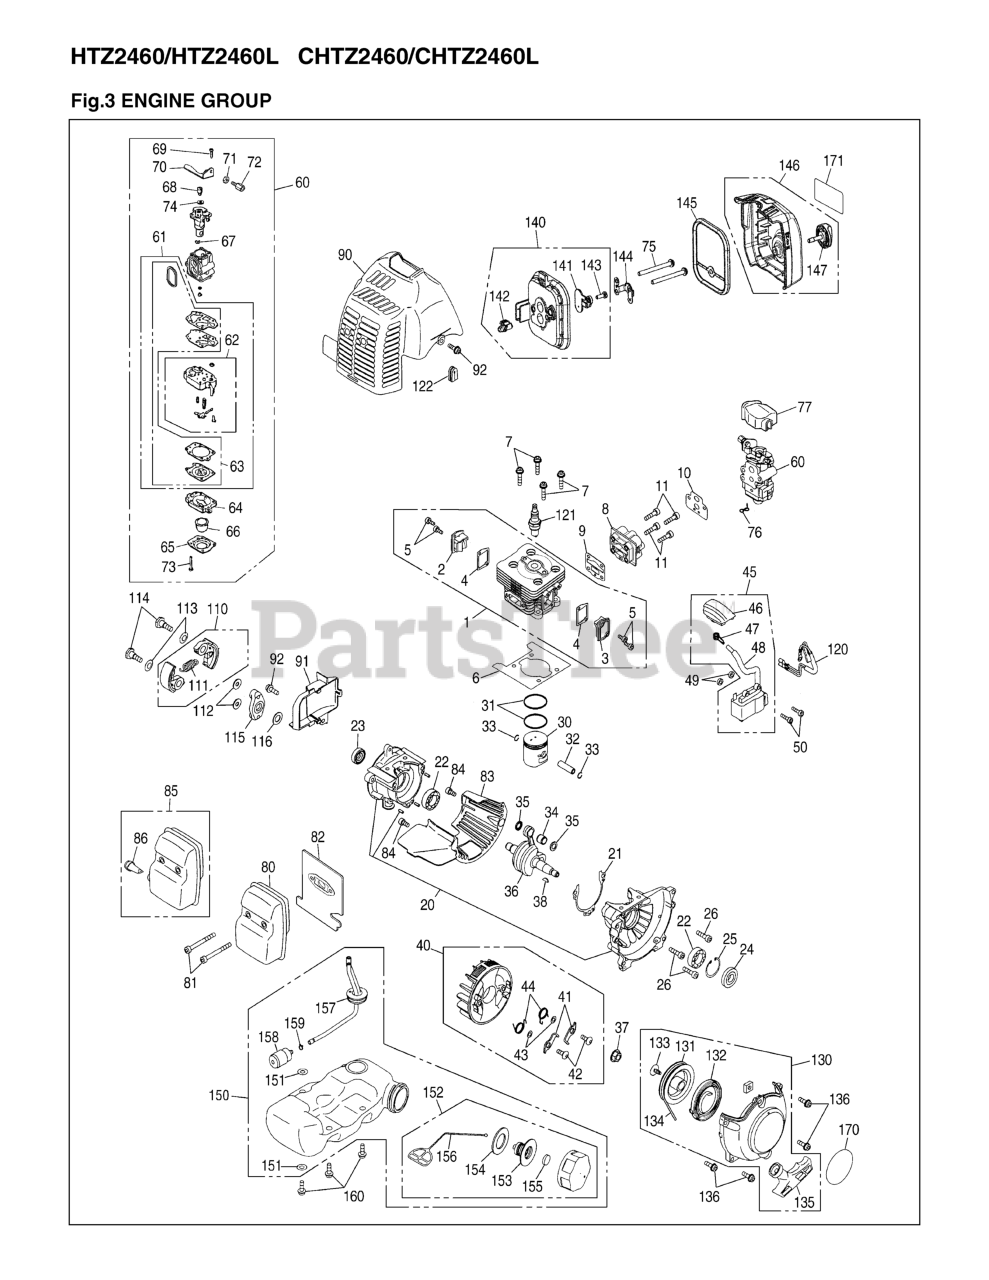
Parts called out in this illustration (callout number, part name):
1	CYLINDER-C
2	COVER, TR-S
3	COVER, TR-F
4	GASKET, TR
5	BOLT
6	GASKET,BASE
7	BOLT
8	INSULATOR
9	INSULATOR GASKET
10	GASKET, CARB
11	BOLT, TORX
20	CRANKCASE COMP.(
21	GASKET, CASE
22	BEARING MAIN
23	SEAL
24	SEAL, OIL (RPLS
26	BOLT (RPLS 28501
31	RING, PISTON
32	PIN, PISTON
33	RING, SNAP (RPLS
35	WASHER
36	SHAFT COMP. (RPL
37	NUT (RPLS 1140-4
38	KEY
40	ROTOR ASSY
41	PAWL
42	SCREW
43	WASHER
45	COIL-A
46	CAP(RPLS 4810721
50	BOLT TORX
60	CARBURETOR ASSY.
61	REBUILD KIT
62	BODY, PUMP
63	GASKET KIT
64	BODY, PURGE
65	COVER, PUMP
66	PUMP, PRIMING
72	SCREW
73	SCREW
74	WASHER
75	BOLT TORX
76	CLIP
77	COVER
81	BOLT
82	MUFFLER GASKET
84	BOLT
90	COVER,ENGINE
91	DEFLECTOR
92	BOLT, TORX
110	CLUTCH ASSY
112	WASHER
113	WASHER
115	PLATE, CLUTCH
116	WASHER
121	SPKPLUG(CMR7H)(R
122	GROMMET
130	RECOIL-A
132	SPRING, SPIRAL
133	SCREW (RPLS 1850
135	KNOB (RPLS 3330-
136	BOLT, TORX
140	BODY ASSY
141	PLATE CHOKE
142	LEVER CHOKE
143	SCREW (RPLS 5003
145	ELEMENT
146	CLEANER COVER AS
147	CLEANER KNOB
150	TANK ASSY
152	CAP ASSY
153	HOLDER (RPLS 450
154	PACKING
155	FILTER
156	STOPPER
157	PIPE-C
158	FILTER
159	CLIP (RPLS 28413
160	BOLT, TORX
170	LABEL RECOIL
